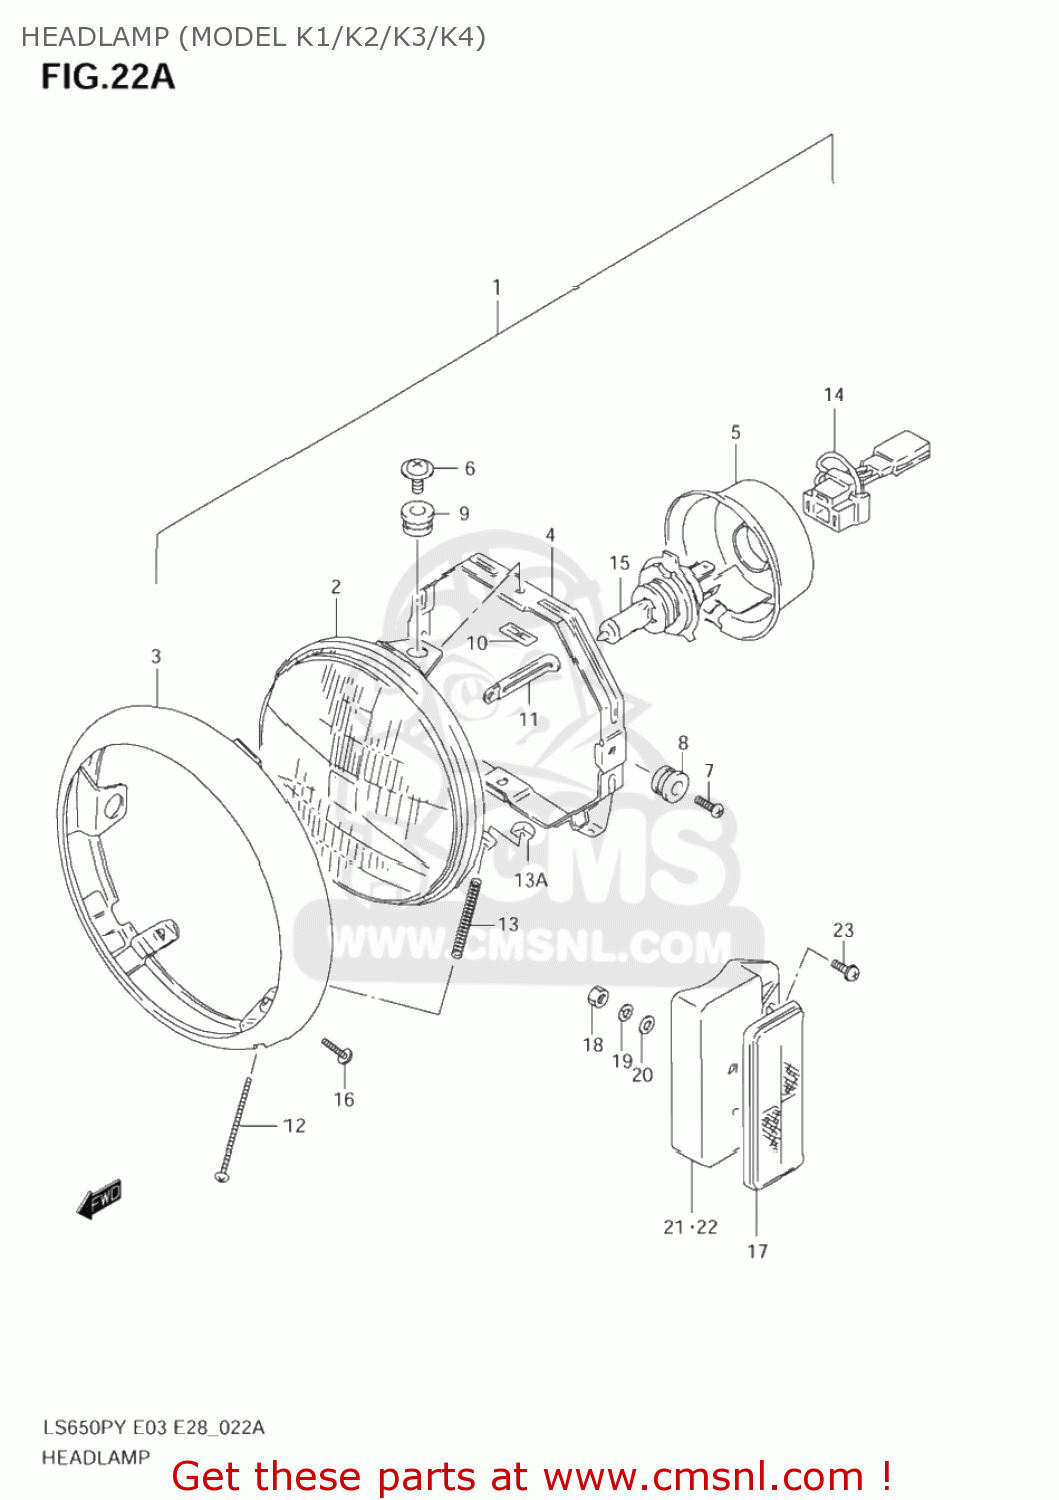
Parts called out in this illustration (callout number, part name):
1	HEADLAMP ASSY
2	UNIT,LAMP
3	RIM
4	RING,MOUNTING
5	COVER
6	SCREW
7	SCREW,MOUNTING
8	CUSHION
9	CUSHION
10	NUT
11	CLAMP(L:65)
12	SCREW,ADJUSTING(4X50)
13	SPRING
13A	NUT,HEADLAMP ADJUST
14	SOCKET
15	BULB(12V60/55W,H4)
16	SCREW
17	REFLEX REFLECTOR,FR SIDE
18	NUT
19	LOCK,WASHER
20	WASHER(5.5X16X1.2)
21	BRACKET,FR SIDE RR,R
22	BRACKET,FR SIDE RR,L
23	SCREW(5X12)
